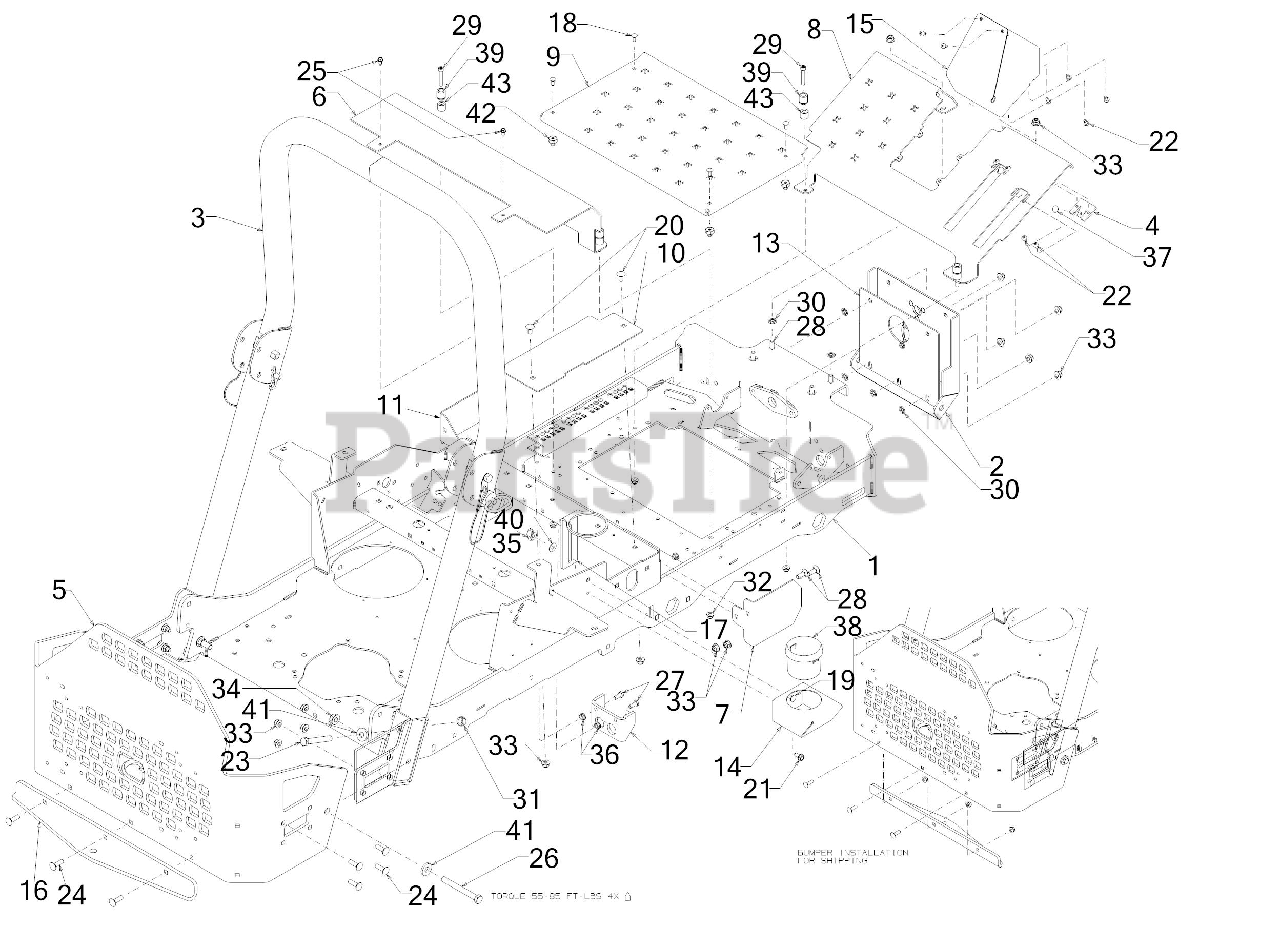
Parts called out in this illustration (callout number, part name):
1	FRAME ASSEMBLY
2	AXLE COVER ASSEMBLY
3	FOLDING ROPS ASSEMBLY
4	STOP BRACKET
5	REAR BUMPER
6	SEAT BOX COVER
8	FRONT PEDAL COVER
9	FLOOR BOARD
10	SEAT PANEL COVER RH
11	SEAT BOX END COVER (LH)
12	FRONT DECK LIFT MOUNTING BRACKET
13	FRONT AXLE PLATE
14	LOWER CUP HOLDER
15	EPS COLUMN COVER
16	HITCH BRACKET
17	UPPER CUP HOLDER BRACKET
18	CARRIAGE BOLT 1/4-20 x .62
19	CARRIAGE BOLT 5/16-18 x 1.00
20	CARRIAGE BOLT 3/8-16 x .750 GR5
21	SCREW 5/16-18 x .750
22	SCREW 1/4-20 x .5
23	SCREW 1/2-20 x 3.50 GR5
24	CARRIAGE BOLT 3/8-16 X1.25 GR5
25	SCREW 1/4-20 X.500
26	SCREW 1/2-13 x 4.5 GR 5
27	SCREW 5/16-18 x .75 GR5
28	CARRIAGE BOLT 3/8-16 x 1.00 GR5
29	SCREW 5/16-18X1.75 GR5
31	HEX NUT
32	FLANGE LOCK NUT 5/16-18
35	WING NUT 5/16-18
36	FLANGE NUT
37	RATCHET CLIP
39	RADIAL BUMPER
40	FLAT WASHER
41	FLAT WASHER .531 x 1.25 x .181
42	SHOULDER SPACER
